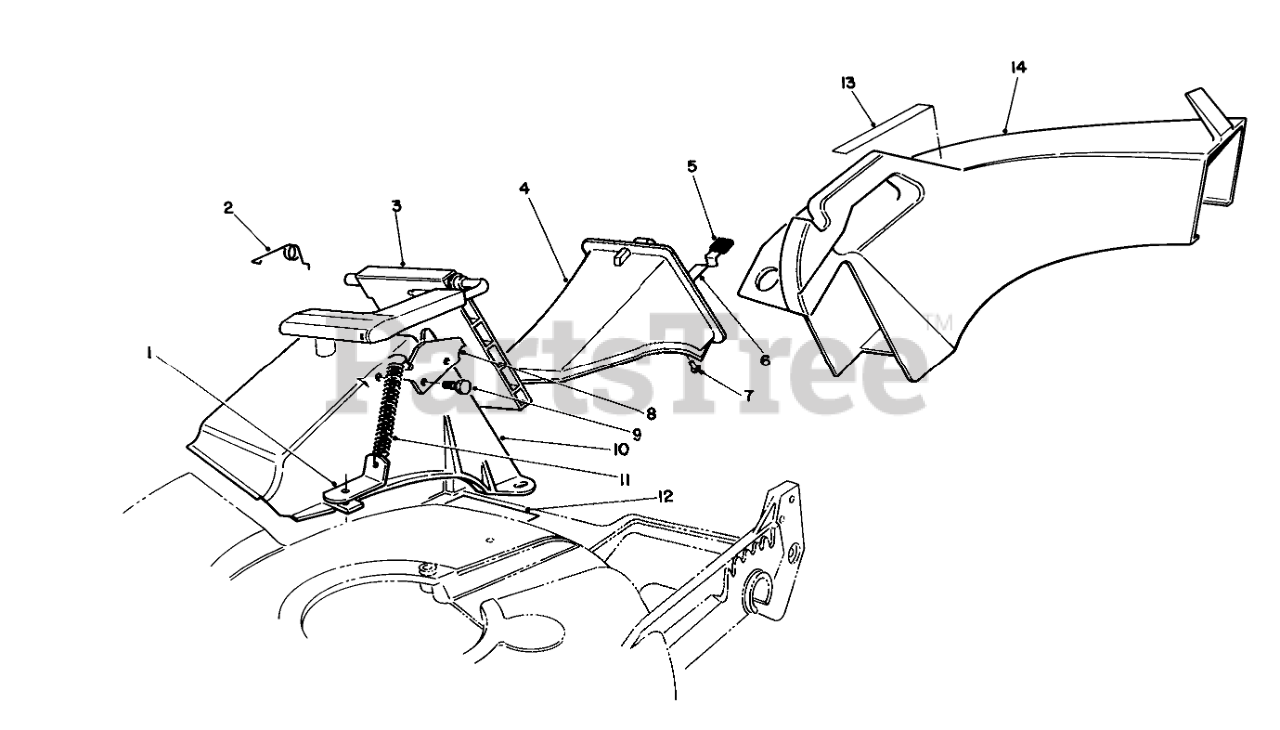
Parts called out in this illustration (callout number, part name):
1	Bracket-Spring
2	RETAINER-DOOR
3	DOOR ASSEMBLY
4	Plug Assembly (Incl. Ref. #5-7)
5	GRIP-LATCH
6	LATCH-PLUG, DISCHARGE
7	RIVET-HEAD, FLAT
8	DOOR LATCH PLATE
9	SCREW-PLASTITE
10	DISCHARGE TUNNEL
11	SPRING-DOOR
12	DECAL - CAUTION
13	DECAL - WARNING
14	CHUTE
